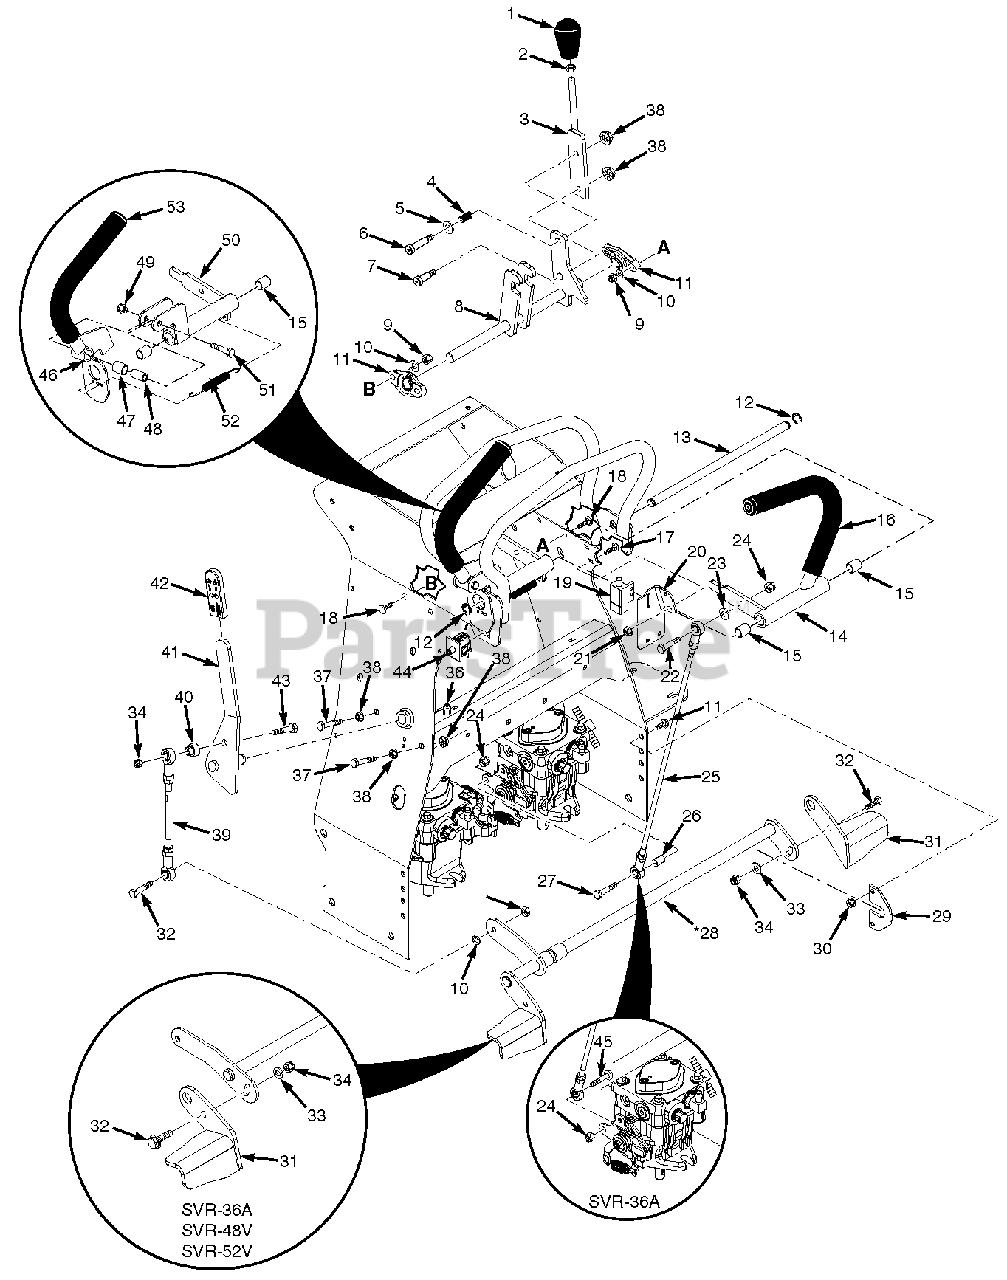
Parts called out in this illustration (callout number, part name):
1	Knob, Soft Touch
2	Nut, Jam 3/8-16
3	Handle Weldment
4	Spring, Neutral Lever
5	Flatwasher, 3/8-.406 x .812 x .065
6	Bolt, Shoulder 3/8 x 1"
7	Bolt, Shoulder 3/8 x .375
8	Lock Weldment, Neutral
9	Nut, Elastic Stop 1/4-20
10	Lockwasher, 5/16" Spring
11	Bearing
12	Retaining Ring, .50 External
13	Shaft, Steering Handles
14	Handle Bar Assy., RH
15	Bearing
16	Grip, Control Lever RH
17	Bolt, Carriage 1/4-20 x 3/4"
18	Bolt, Carriage 1/4-20 x 1"
19	Switch, Interlock
20	Bracket, Neutral Switch
21	Nut, Serrated Flange 1/4-20
22	Bolt, Hex Head 5/16-18 x 1-1/4"
23	Flatwasher, 5/16-.344 x .688 x .065
24	Nut, Elastic Stop 5/16-18
25	Linkage Assembly
26	Spacer, Pump
27	Bolt, Hex Head 5/16-18 x 1-3/4"
28	Bellcrank, Brake Weldment - SVR-36A
28	Bellcrank, Brake Weldment - SVR-48V/52V
28	Bellcrank, Brake Weldment - SVR-61V
29	Brake Keeper Plate
29	Brake Keeper Plate - SVR-61V
30	Nut, Serrated Flange 5/16-18
31	Brake Paddle Weldment, LH
31	Brake Paddle Weldment - SVR-61V
32	Bolt, Hex Head 3/8-16 x 1-1/4"
33	Flatwasher, 3/8-.438 x 1.0 x .083
34	Nut, Elastic Stop 3/8-16
35	Nut, Center Lock 3/8-16
36	Retaining Ring, .625 External "E"
37	Bolt, Hex Head 5/16-18 x 1-1/2"
38	Nut, Serrated Flange 5/16-18
39	Linkage Assembly, Brake
40	Spacer
41	Brake Lever w/Grip
41	Brake Lever w/Grip - SVR-61V
42	Grip, Brake Lever
43	Bolt, Hex Head 3/8-16 x 2"
44	Switch, Double Pole (N.O. / N.O.)
45	Capscrew, Button Head 5/16-18 x 1"
46	Steering Handle Assy., LH w/Grip
47	Bearing
48	Spacer, Handle
49	Nut, Elastic Stop 5/16-18
50	Steering Pivot Assy
51	Bolt, Hex Head 5/16-18 x 1-3/4"
52	Spring, Handle
53	Grip, Control Lever LH
